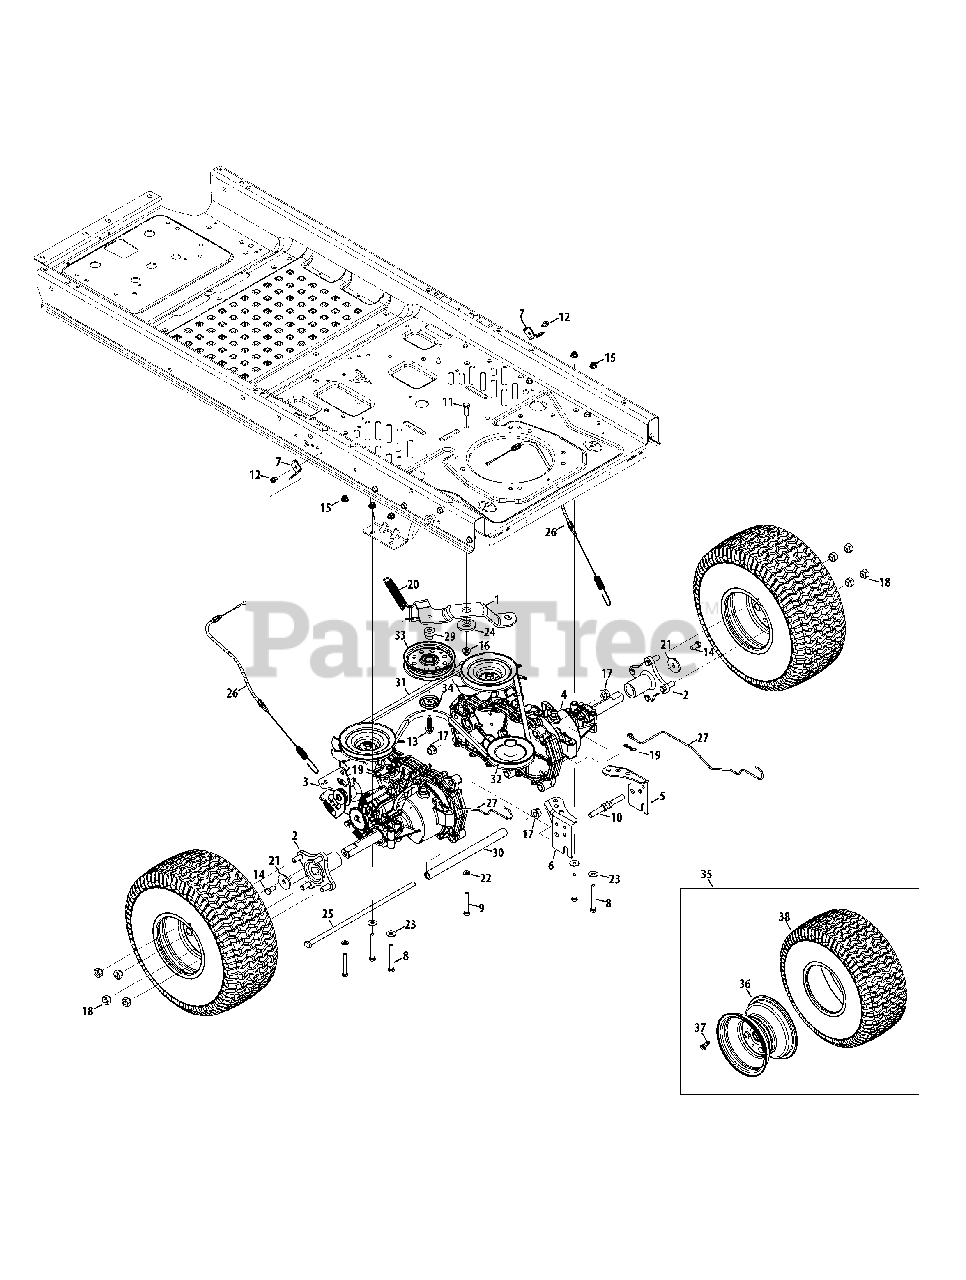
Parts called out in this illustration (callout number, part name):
1	BRACKET, Idler
2	ASSEMBLY, Wheel Hub
3	ASSEMBLY, Hydro Transmission (LH)
4	ASSEMBLY, Hydro Transmission (RH)
5	BRACKET, Transmission Mounting (RH)
6	BRACKET, Transmission Mounting (LH)
7	BRACKET, Brake Cable
8	SCREW, 5/16-18 X 2.75, Hex
9	SCREW, 5/16-18 X 2.25, Hex, GR5
10	SCREW, 7/16-20 X 1.75 GR 5
11	SCREW, 3/8-16 X 1 GR5
12	SCREW, Hex Head, 1/4-20 X 1/2
13	SCREW, 3/8-16 X1.250
14	SCREW, 3/8-16 X .75 GR 5
15	NUT, 5/8-18 Hex Flange
16	NUT, 3/8-16, Flanged Lock, GR5, Zinc/Clear
17	NUT, Flange Lock
18	NUT, 7/16-14, Lug
19	PIN, 1/4-5/16, Bow Tie Cotter
20	SPRING, .75 DIA X 5.87 RZT/F, Extension
21	WASHER, .390X1.500X.134, Flat
22	WASHER, 5/16, Flat
23	WASHER, 5/16, Flat
24	SPACER, Shoulder
25	ROD, Support Tube
26	CABLE, Park Prake
27	ROD, Hydro Bypass
28	HOOK, Idler Spring
29	SPACER, Shoulder
30	TUBE, Support
31	BELT, A X 67, Transmission Drive
32	PULLEY, Transmission Drive
33	PULLEY, 4.25 DIA, Idler
34	PULLEY CAP, Idler Pulley
35	ASSEMBLY, Wheel (18 X 8.5-8)
36	ASSEMBLY, Rear Rim
37	VALVE, Stem - Tubless
38	TIRE, 18 X 9.5 X 8 SQ SH
